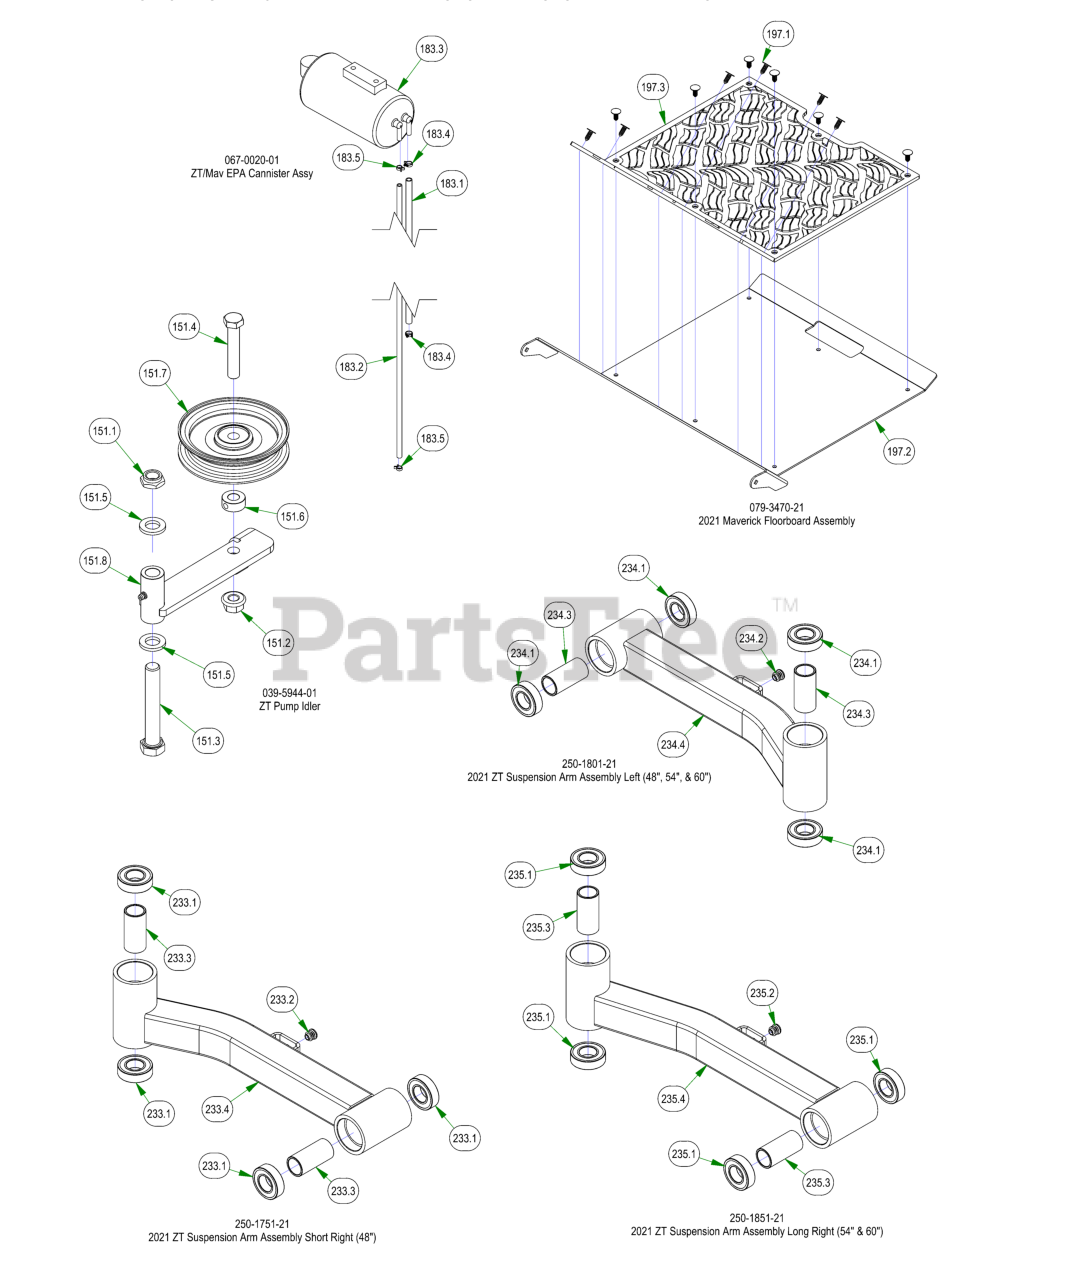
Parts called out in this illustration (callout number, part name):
151	ZT Pump Idler
151.1	5/8-11 NYLON INSERT JAM LOCKNUT ZINC
151.2	1/2-13 NYLON INSERT FLANGE LOCKNUT ZINC
151.3	5/8-11 X 4 HEX CAP SCREW (GR.8) ZINC YELLOW
151.4	1/2-13 X 2-3/4 HEX CAP SCREW (GR.5) ZINC
151.5	.635 ID X 1.120 OD X .140 THICK FLAT WASHER NYLON
151.6	1/2 SOLID SHAFT COLLAR (W/1 SET SCREW) ZINC
151.7	4 3/4" Idler Pulley
151.8	Pump Idler Bracket
165.3	Fuel Line 4" Section with Clamps
165.3.1	1/4 Fuel Hose Clamp
165.3.2	4" 1/4 Fuel Line
166.3	Fuel Line 4" Section with Clamps
166.3.1	1/4 Fuel Hose Clamp
166.3.2	4" 1/4 Fuel Line
183	ZT/Mav EPA Cannister Assy
183.1	1/4" Vinyl Tubing, 46" Long
183.2	3/16" Vinyl Tubing, 55" Long
183.3	Carbon Canister
183.4	3/16 Vinyl Clamp
183.5	3/16" Vinyl Hose Clamp
197	2021 Maverick Floorboard Assembly
197.1	Ratchet Fastener
197.2	2018 Maverick Floorboard
197.3	2021 Maverick Floor Mat W/ Reaper Tread
233	2021 ZT Suspension Arm Assembly Short Right (48")
233.1	1641 BEARING W/2 CONTACT RUBBER SEALS
233.2	5/8 Round Insert
233.3	2016 Front Bearing Spacer
233.4	2021 ZT RH Front Arm - Short
234	2021 ZT Suspension Arm Assembly Left (48", 54", & 60")
234.1	1641 BEARING W/2 CONTACT RUBBER SEALS
234.2	5/8 Round Insert
234.3	2016 Front Bearing Spacer
234.4	2021 ZT LH Front Arm
235	2021 ZT Suspension Arm Assembly Long Right (54" & 60")
235.1	1641 BEARING W/2 CONTACT RUBBER SEALS
235.2	5/8 Round Insert
235.3	2016 Front Bearing Spacer
235.4	2021 ZT RH Front Arm - Long
